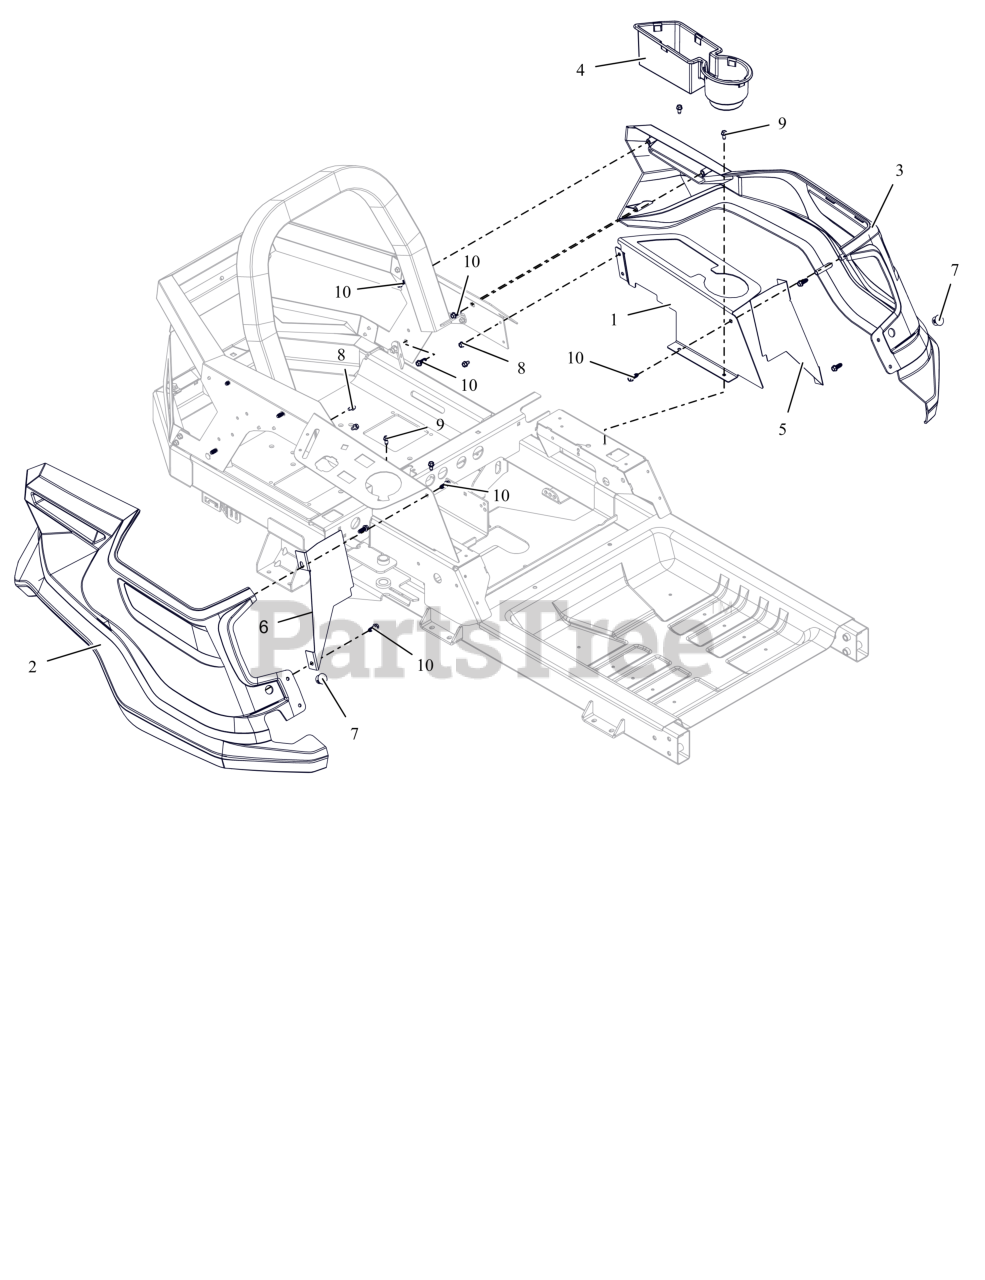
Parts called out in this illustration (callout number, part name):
1	PANEL, LEFT SIDE FENDER MOUNT
2	FENDER, RH IKON
3	FENDER, LH IKON
4	INSERT, CUP/STORAGE HOLDER
5	PLATE, LH BLOCKER
6	PLATE, RH BLOCKER
7	PLUG, HOLE .75 (BLACK)
8	SCR,TAP .25-20X.375 HWH TR ZCC
9	SCR-TAP .25-20X.50 HWH ZCC
10	SCR-.312X.75 #14H H/W/H H/L CZ
